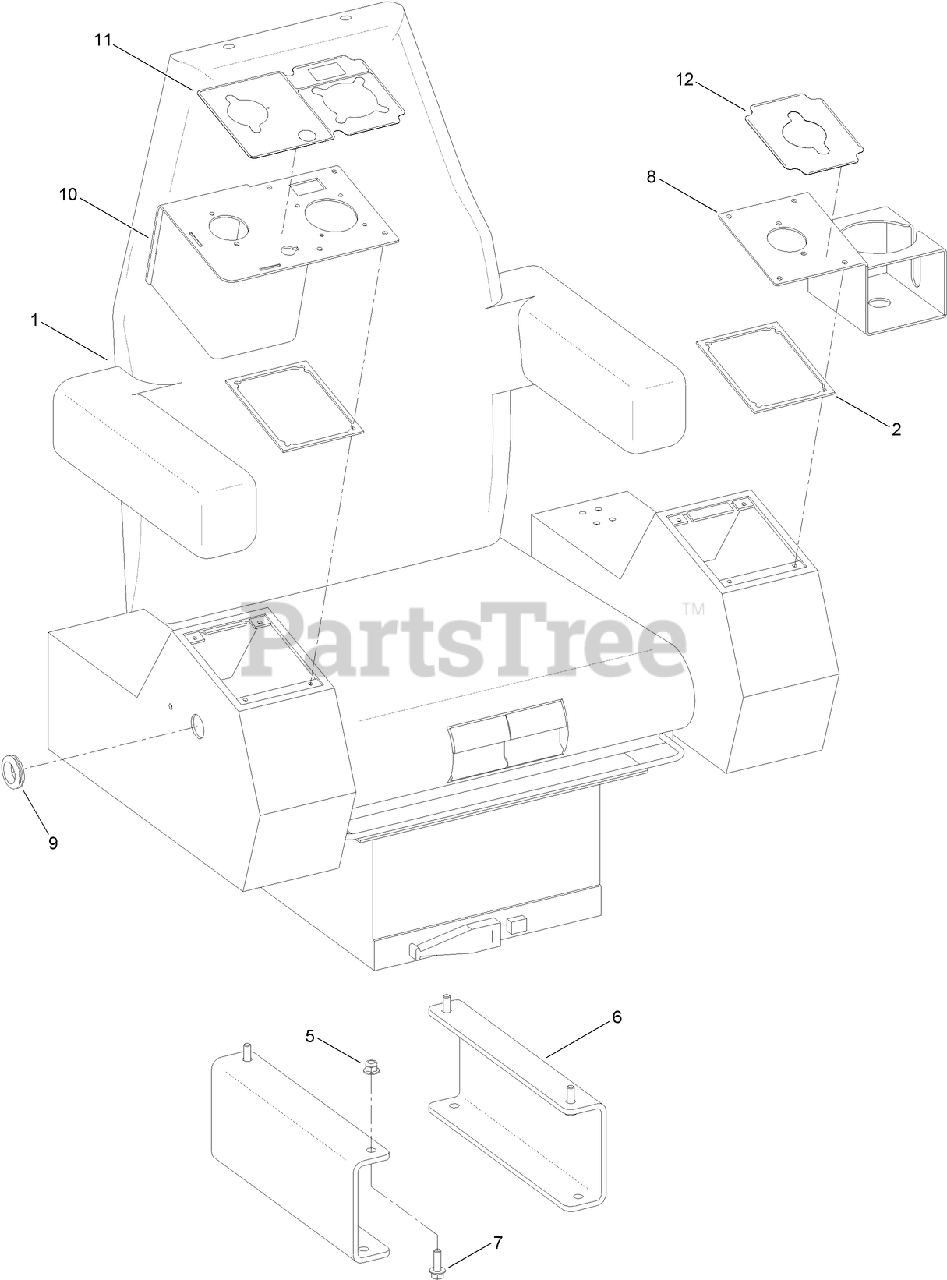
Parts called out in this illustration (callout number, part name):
1	ARMCHAIR-OPERATOR
2	PLATE-SPACER
5	NUT-TORQUE, PREVAILING
6	RISER-OPERATOR SEAT
7	SCREW-HHF
8	CUP-HOLDER
9	GROMMET
10	MOUNT-JOYSTICK
11	DECAL-JOYSTICK, RH
12	DECAL-CONTROL, DRIVE (GROUND)
